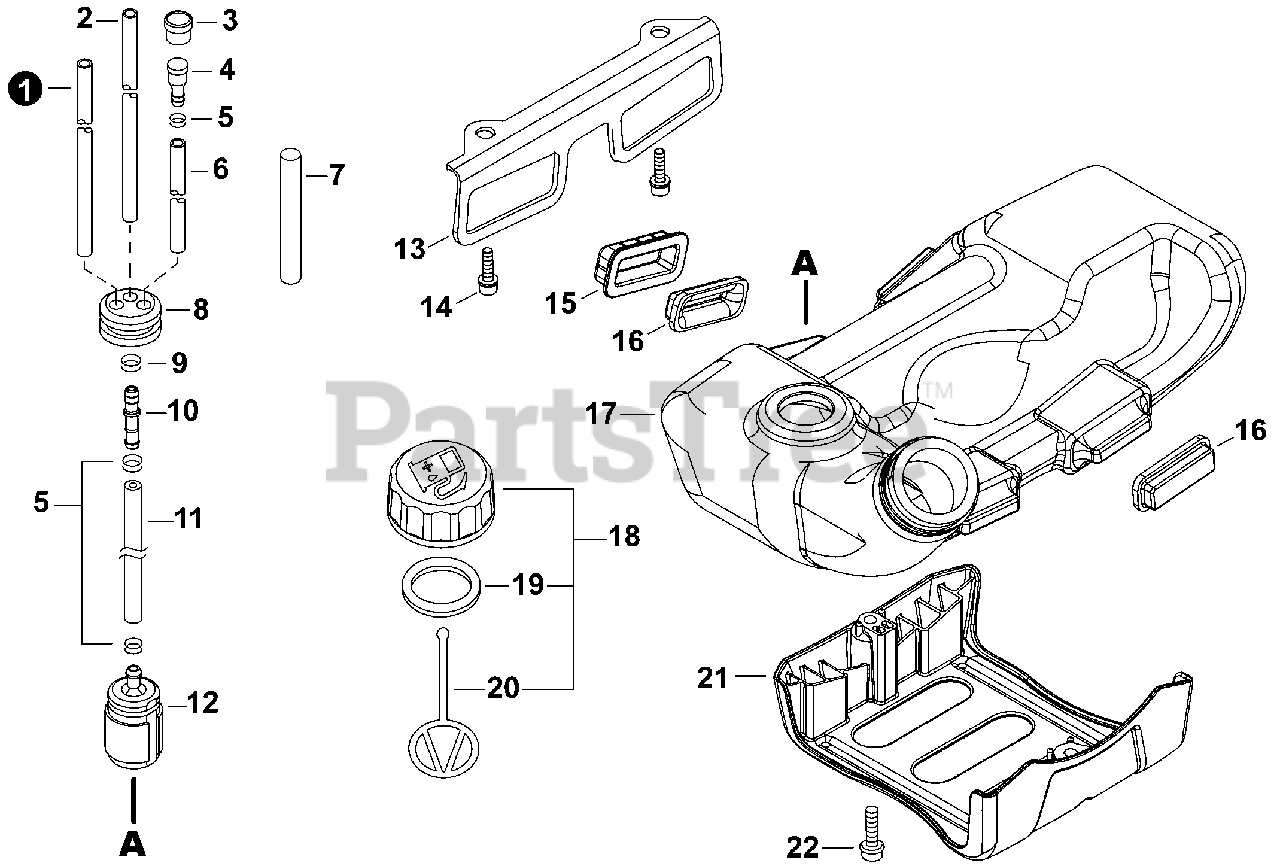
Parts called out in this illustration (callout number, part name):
1	PIPE, FUEL
2	PIPE, FUEL 3x5x180
3	HOLDER, VENT
4	VENT ASSY
6	PIPE, FUEL 3x6x140 BLACK
7	TUBE, INSULATOR 8x9x111
8	GROMMET, FUEL
9	CLIP 5.5
10	CONNECTOR, PIPE
11	PIPE, FUEL 3x6x130 BLACK
12	FILTER, FUEL
13	BRACKET, FUEL TANK
14	BOLT, TORX 5x16
15	HOLDER, CUSHION
16	CUSHION, FUEL TANK
17	TANK, FUEL
18	CAP ASSY, FUEL
19	GASKET, FUEL CAP
20	CONNECTOR, CAP L= 123
21	GUARD, FUEL TANK
22	BOLT, TORX 5x16
